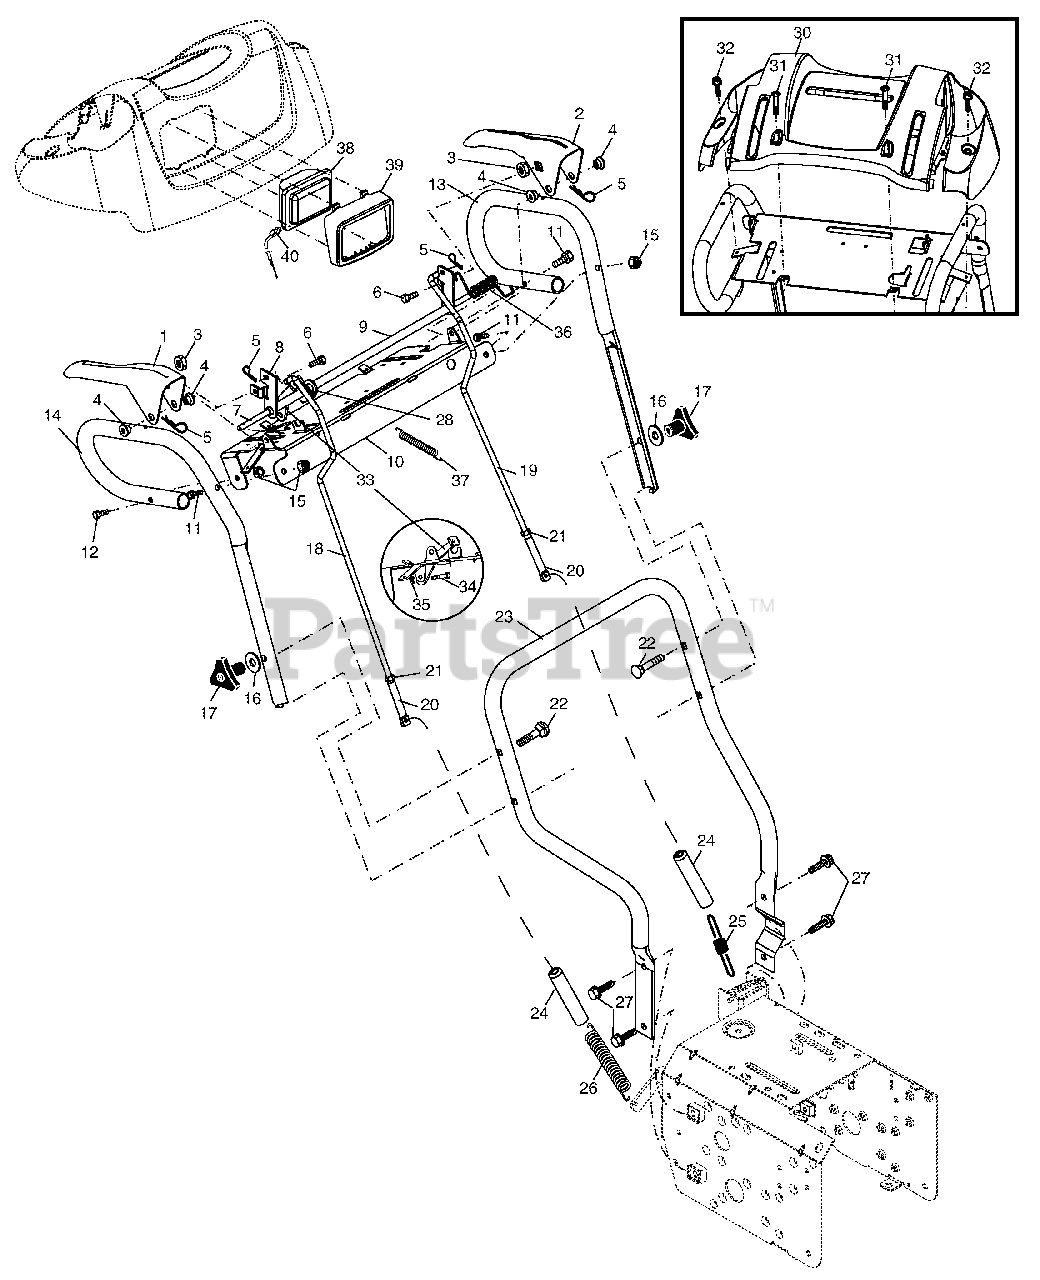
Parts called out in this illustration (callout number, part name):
1	Lever, Auger Control, RH
2	Lever, Traction Drive Control, LH
3	Nut, Cage 1/4-20
4	Bushing, Flange
5	Retainer, Hairpin
6	Screw, Hex Head 1/4-20 x 3/4
7	Rod, Interlock
8	Tube Assembly, Interlock, RH
9	Tube Assembly, Interlock, LH
10	Panel, Control
11	Screw, Hex Head 5/16-18 x 1-1/2
12	Screw, Hex Head 5/16-18 x 1-3/4
13	Handle Tube, LH
14	Handle Tube, RH
15	Nut, Lock 5/16-18
16	Washer, Flat 3/8
17	Knob, Handle
18	Rod, Auger Control
19	Rod, Traction Control
20	End, Control Rod
21	Nut, Hex, Jam 5/16-18
22	Bolt, Carriage 3/8-16 x 2-1/4
23	Handle Tube, Lower
24	Sleeve, Spring
25	Spring, Traction Drive
26	Spring, Auger Control
27	Screw, Hex Head 3/8-16 x 1
28	Clip, Panel
30	Console, Panel
31	Screw, Hex Head, Tapping #10-24 x 1-1/4
32	Screw, Hex Head, Tapping #10-24 x 1/2
33	Latch, Interlock
34	Bolt, Shoulder
35	Nut, Lock 1/4-20
36	Spring, Torsion
37	Spring, Interlock
38	Headlight, Halogen
39	Bezel, Headlight
40	Harness, Headlight (Halogen)
